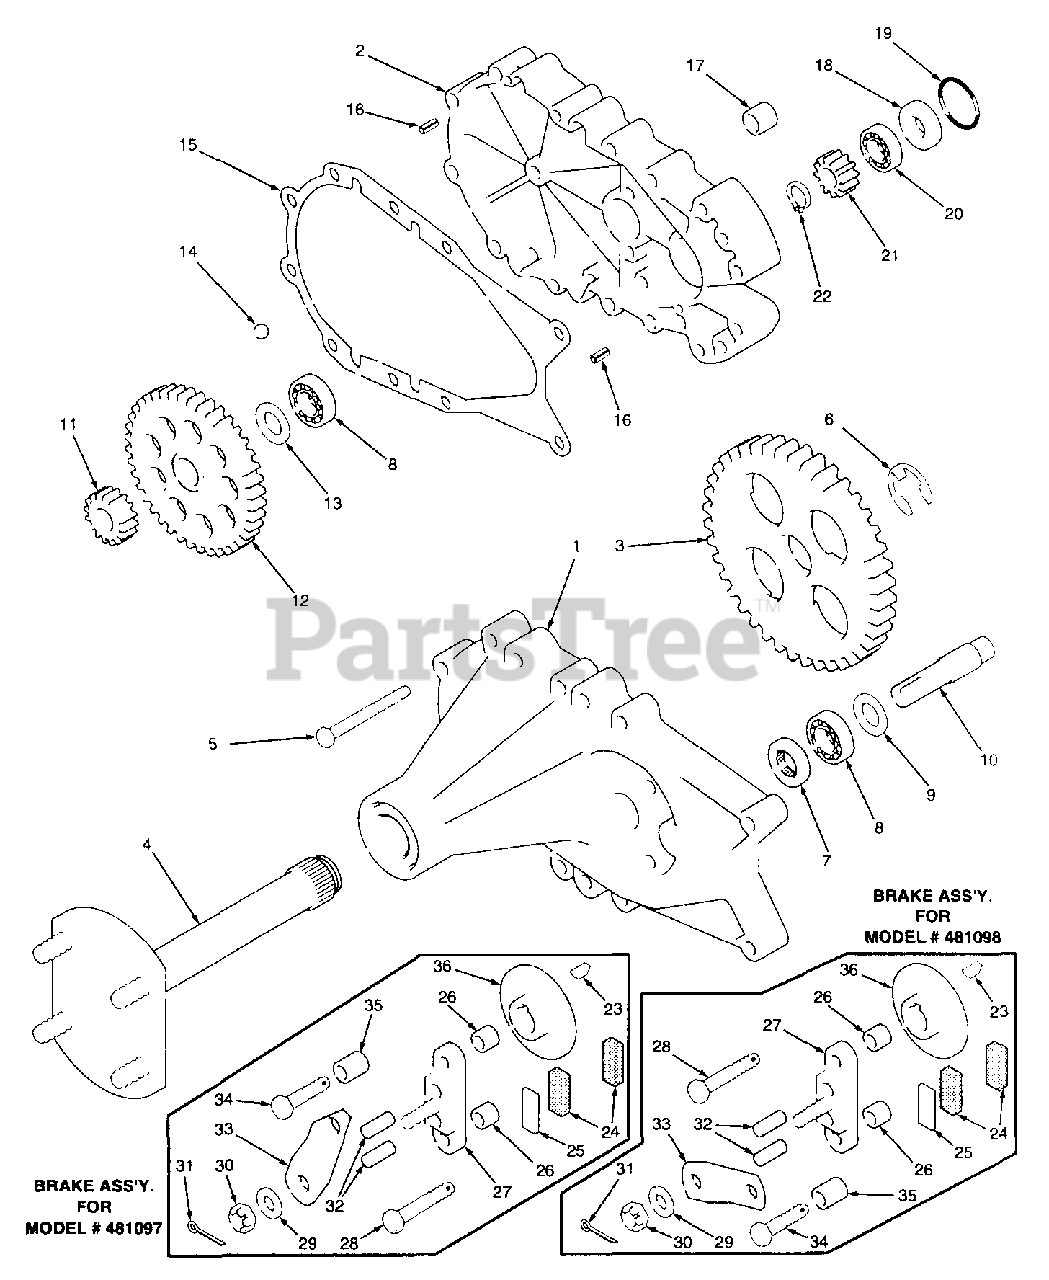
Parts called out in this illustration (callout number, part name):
1	Axle Housing Assembly
2	Hydro Mount Housing
3	Splined 72 Tooth Final Drive Gear
4	Axle Shaft Assembly
5	Bolt, 1/4-20 x 2-1/2" Hex Head
6	E-Ring .875
7	Oil Seal, 1.25 x .625
8	Ball Bearing, .62 ID x 1.38 x .44
9	Washer, HT .62 ID x 1.0 OD x .05 Thick
10	Brake Shaft (Splined)
11	Splined Reduction Gear, 17 Tooth
12	Splined 60 Tooth Gear
13	Washer, HT .62 ID x 1.0 OD x .05 Thick
14	Ball, 3/8" Diameter
15	Gasket, Housing
16	Pin, Spring 3/16" x 1/2" x 12" Long
17	Mounting Spacer
18	Bearing, Spacer
19	O-Ring
20	Ball Bearing, 15mm x 35mm x 11mm
21	Input Gear, 11 Tooth
22	Retaining Ring
23	Key, Hi Pro 3/16 x 5/8
24	Puck, Brake
25	Plate, Puck
26	Brake Spacer
27	Brake Yoke Assembly
28	Bolt, 1/4-20 x 1-1/2" w/Patch
29	Washer, 7/16 x 7/8 OD x .06 HT
30	Nut, Castle 5/16-24 PL
31	Pin, Cotter
32	Pin, Brake Actuating
33	Arm, Brake Actuator (LH Assy.)
33	Arm, Brake Actuator (RH Assy.)
34	Bolt, 1/4-20 x 2-1/2"
35	Spacer, Torsion Spring
36	Disc, Brake
